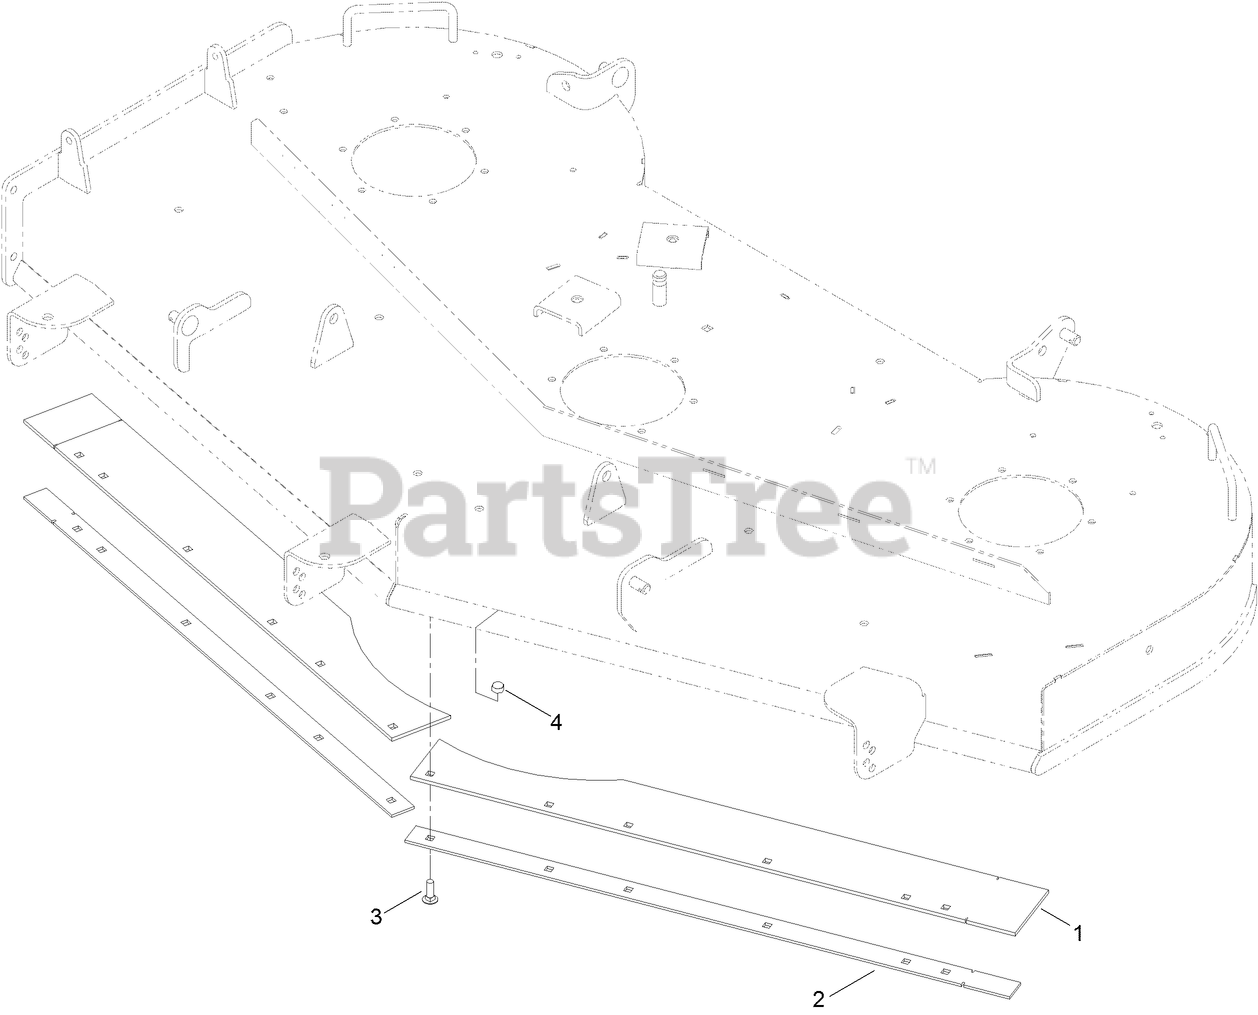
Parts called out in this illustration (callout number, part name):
1	SKIRT-RUBBER, FRONT
2	SKID-SKIRT
3	BOLT-CARR
4	NUT-HEX
